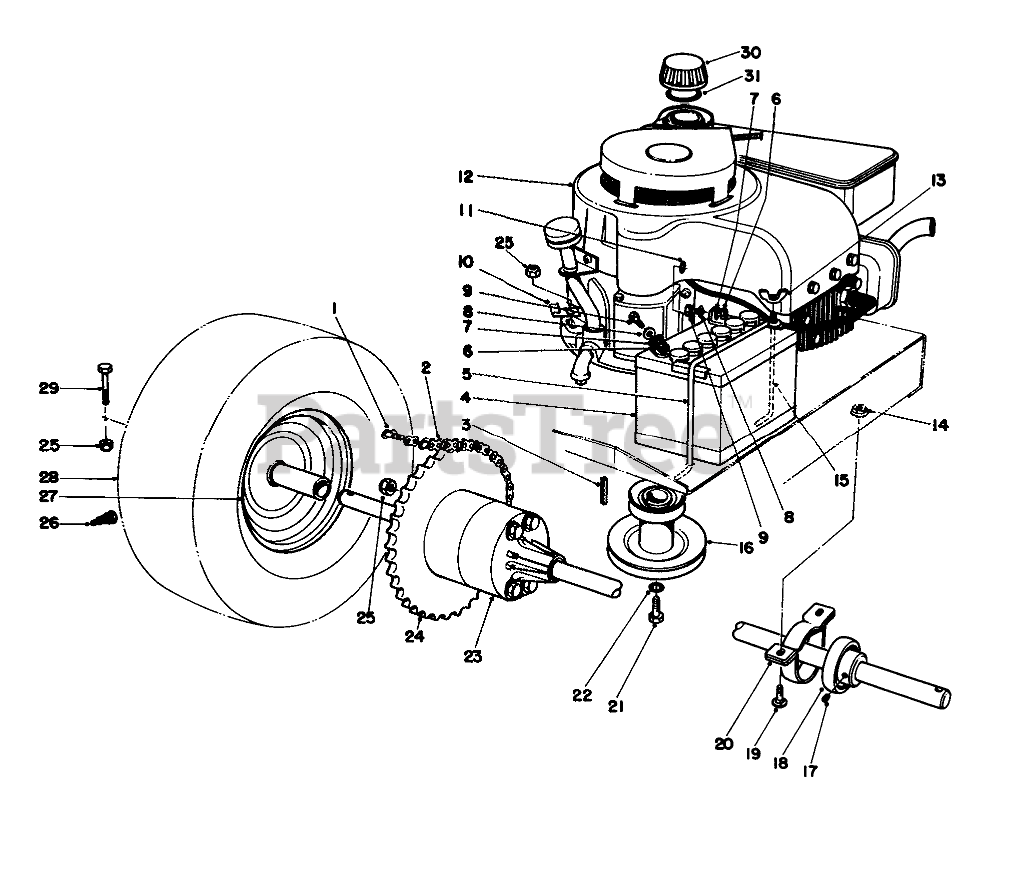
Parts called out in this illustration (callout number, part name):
1	LINK-CONNECTING
2	Chain-Roller (Incl. Ref. #1)
4	BATTERY
5	Battery Clamp
6	NUT-HEX
7	WASHER-LOCK
8	WASHER-FLAT
9	SCREW-HH
10	CLAMP
11	WASHER-LOCK/EXT
13	NUT-WING SPECL
14	NUT-HF
15	ROD-SUPPORT, BATTERY
16	ENGINE PULLEY BO
17	SCREW-HSH
18	Bearing (Incl. Ref. #17)
19	SCREW-CARR
20	RTNR-PILLOW BLK
21	SCREW-HH
22	WASHER-LOCK
23	Differential
24	Sprocket
25	NUT-LOCK, NI
26	STEM-VALVE
27	WHEEL-REAR
28	Tire
29	Bolt
30	Gas Cap Assembly (Incl. Ref. #31)
31	GASKET
